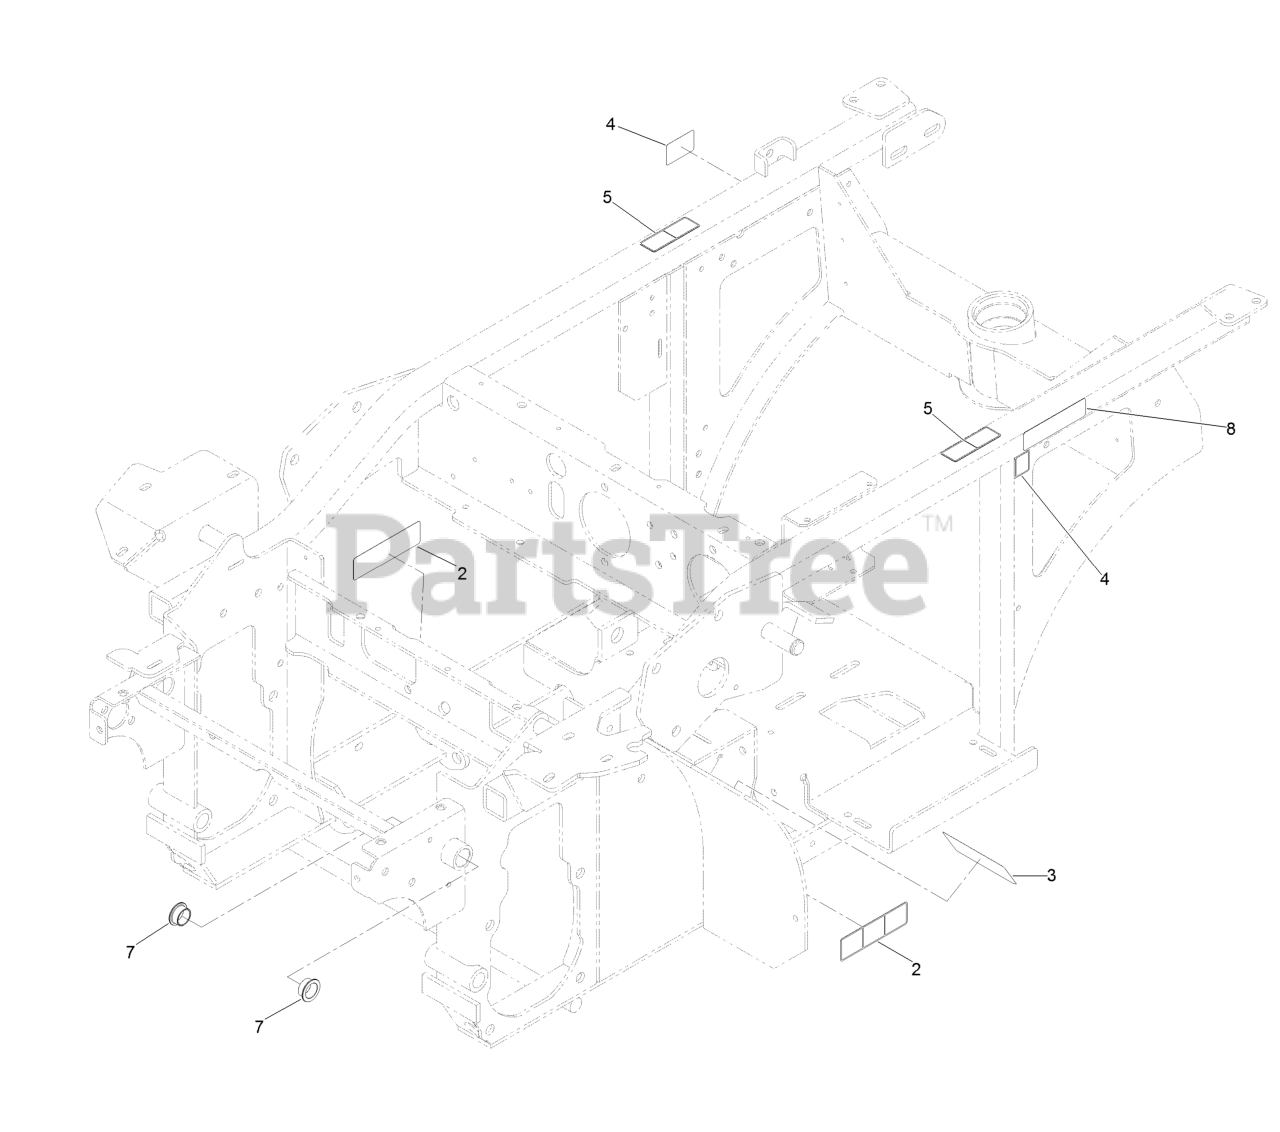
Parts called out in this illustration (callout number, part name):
2	Decal-Missing, Cover
3	Decal-Adjustment, Clutch
4	Decal-Warning
5	Decal-Warning, Pinch Point
7	Bushing-Bronze
8	Decal-Arrester, Spark
